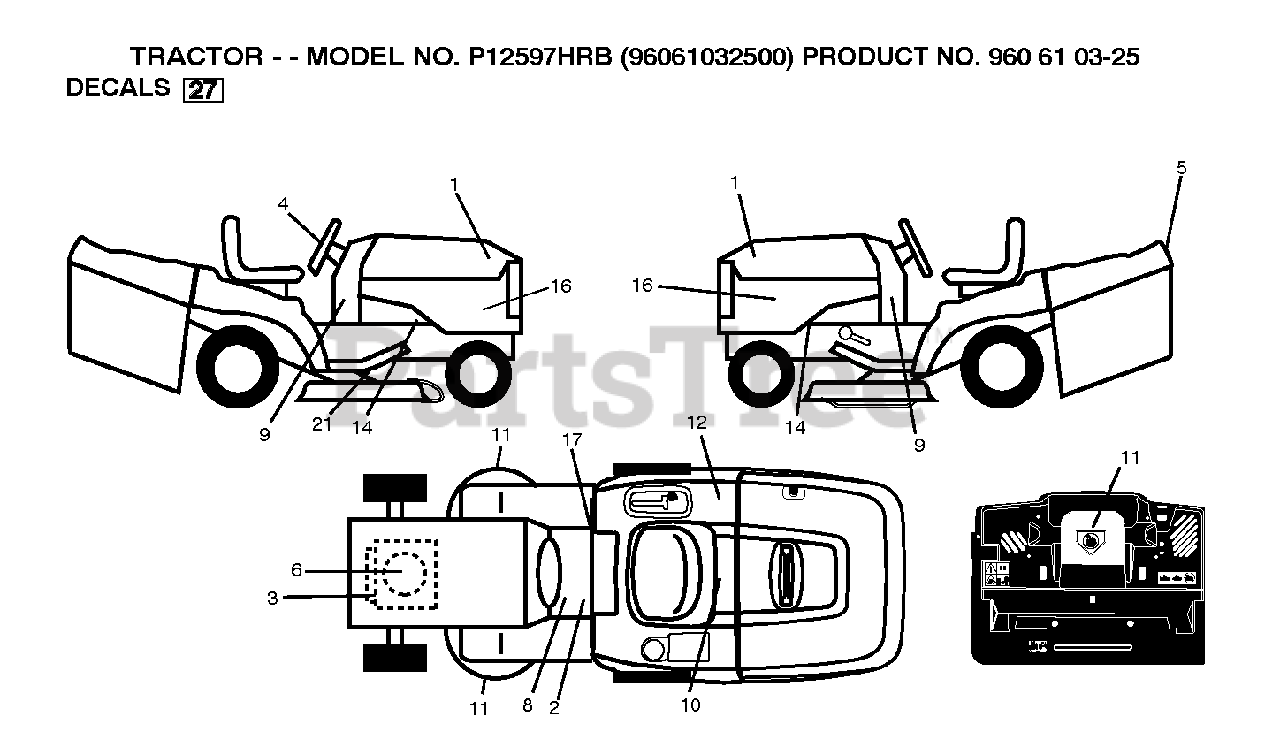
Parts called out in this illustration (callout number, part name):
9	DECAL.CHAS.TURBO
10	DECAL BTRY SYMBOLS
11	DECAL.INTERNATIONL.CUTFINGER
12	Decal, 100 DB/CE
17	DECAL PARK BRAKE
